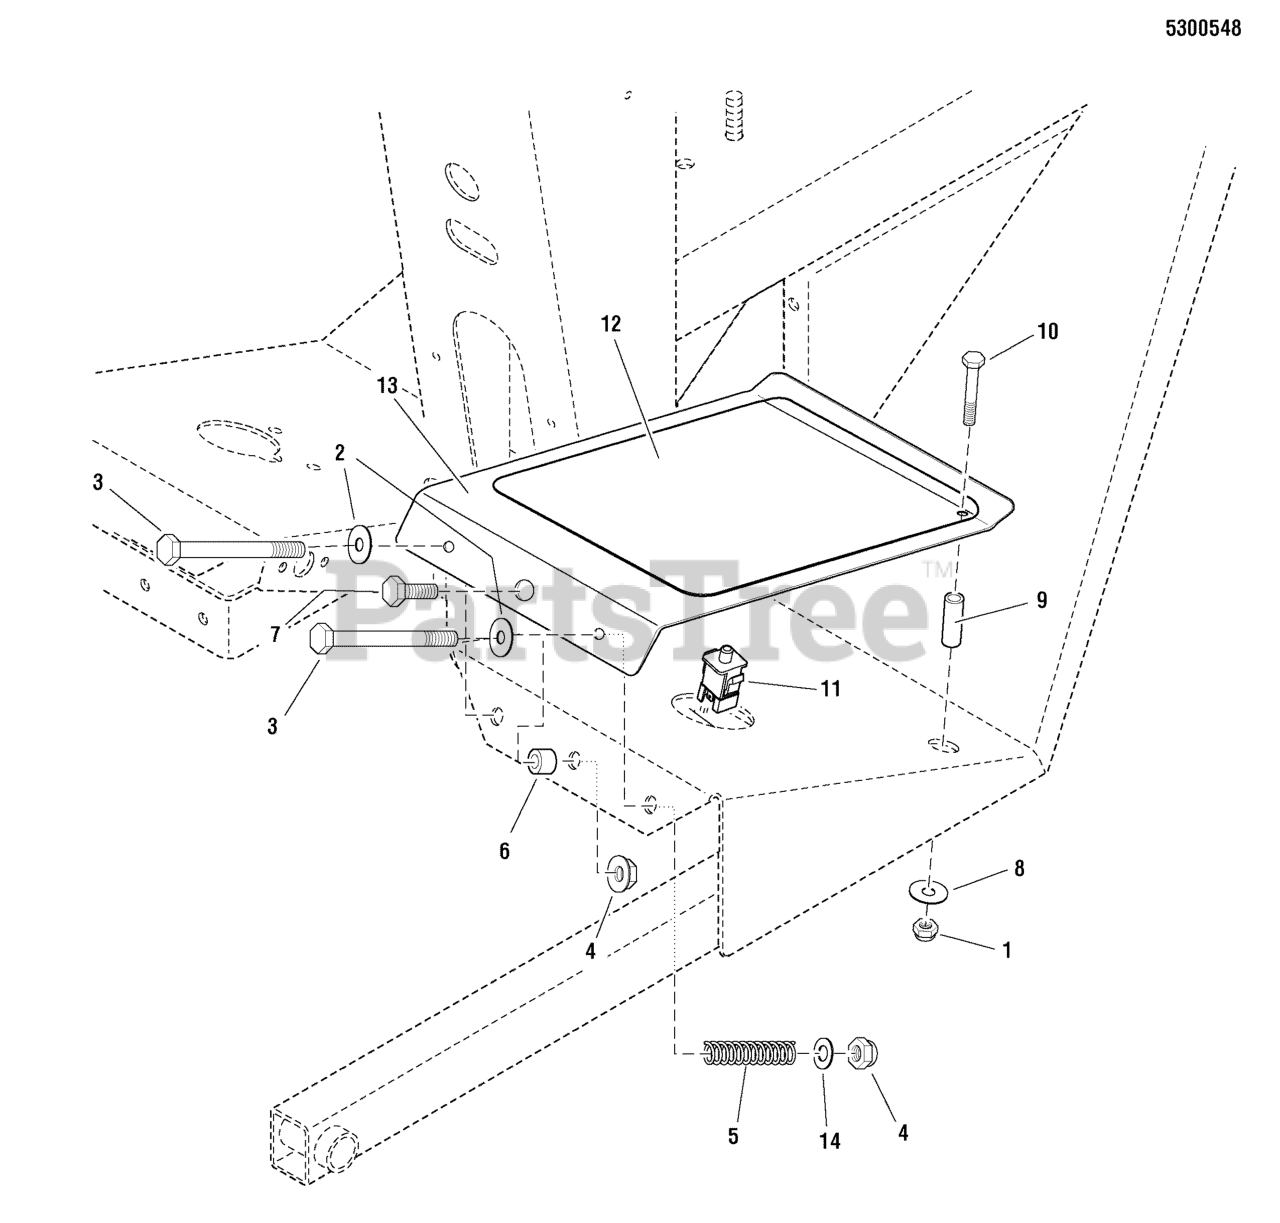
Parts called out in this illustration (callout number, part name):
1	NUT, 5/16-18 HEX NYLOCK FLANGE NUT
2	WASHER, 3/8 SAE
3	BOLT, 3/8-16 X 3" GD5 CZ
4	NUT, 3/8 - 16 HEX NYLOCK FLANGE
5	SPRING-COMP, .594ID X 2.68LG X .080WR
6	INSERT, BEARING, 17MM X 12MM L
7	BOLT, 3/8-16 X 1-1/4" GD5 CZ
8	WASHER, 5/16" Fender
9	BUSHING, BRASS, 3/8 X 5/8 X1.5
10	BOLT, 5/16-18 X 2-1/4" GD5 YZ
11	SWITCH, DP NO/NC SNAP-IN
12	SAFETY WALK, 13.00 X 9.00, LH - TWR
13	PLATE, OPERATOR PRESENCE - RED
14	WASHER, 3/8 SAE
